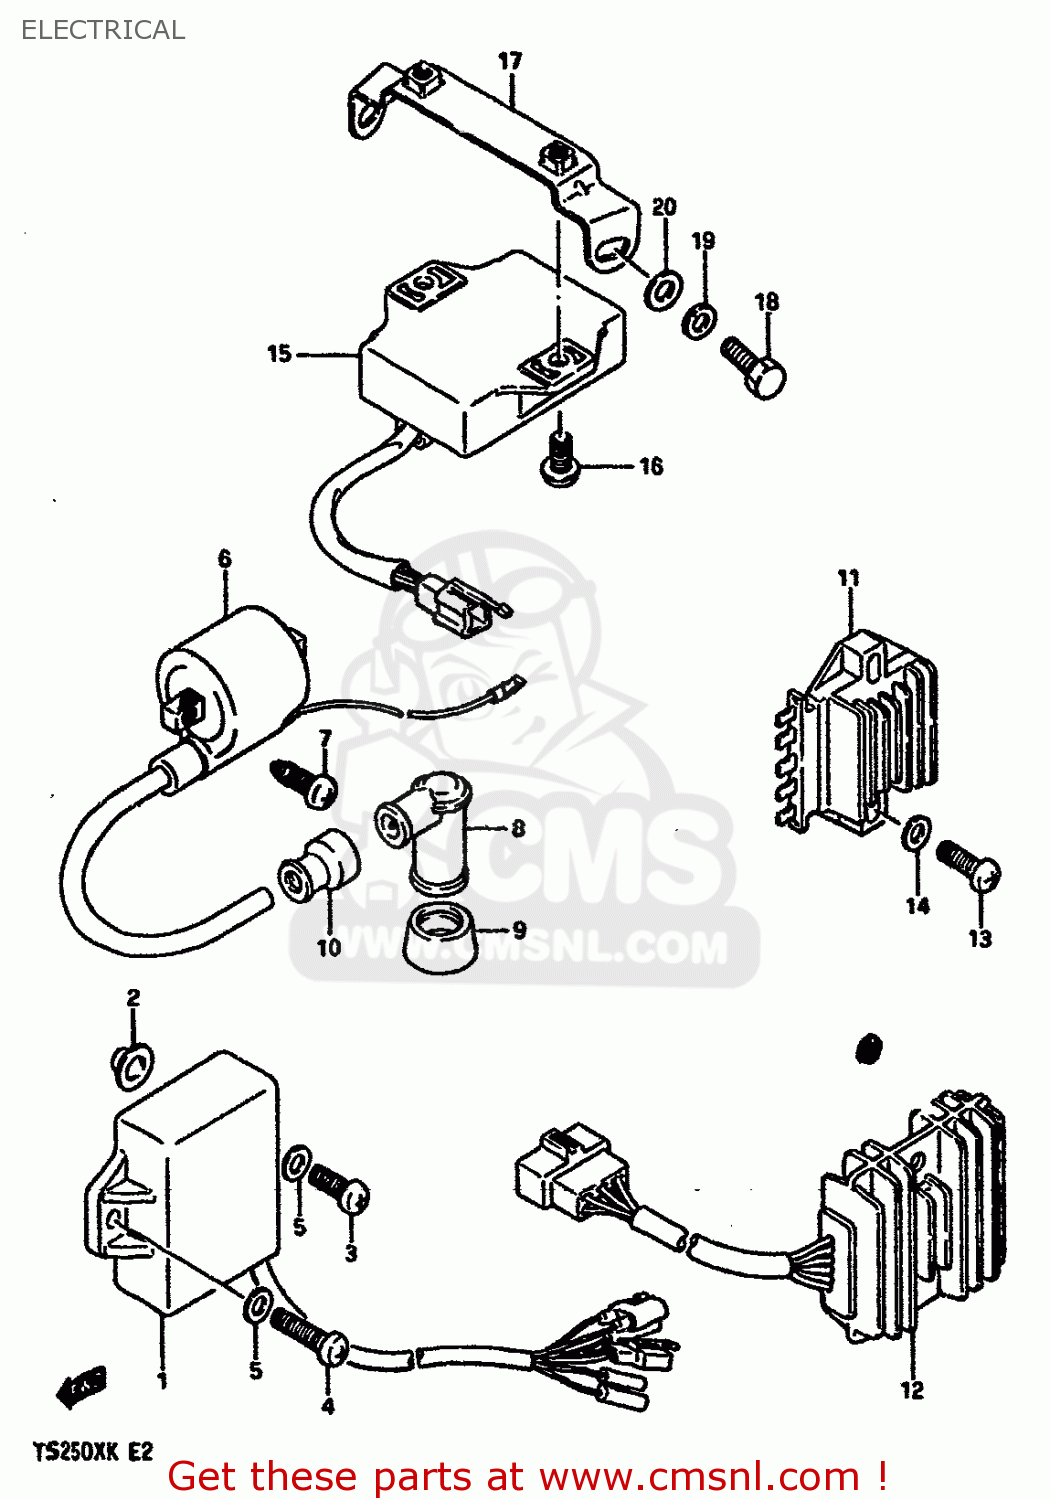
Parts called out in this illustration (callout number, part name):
1	C.D.I UNIT ASSY
2	WASHER
3	SCREW
4	SCREW
5	WASHER
6	COIL ASSY, IGNITION
7	SCREW(6X21)
8	CAP,SPARK PLUG
9	SEAL,SPARK PLUG
10	SEAL,SPARK PLU
11	RECTIFIER ASSEMBLY
12	RECTIFIER ASSY
13	SCREW
14	WASHER, LOWER
15	CONTROL UNIT,SOLENOID
16	SCREW 6X12
17	BRACKET,CONTROL UNIT
18	BOLT
19	WASHER,LOCK
20	WASHER, LOWER
